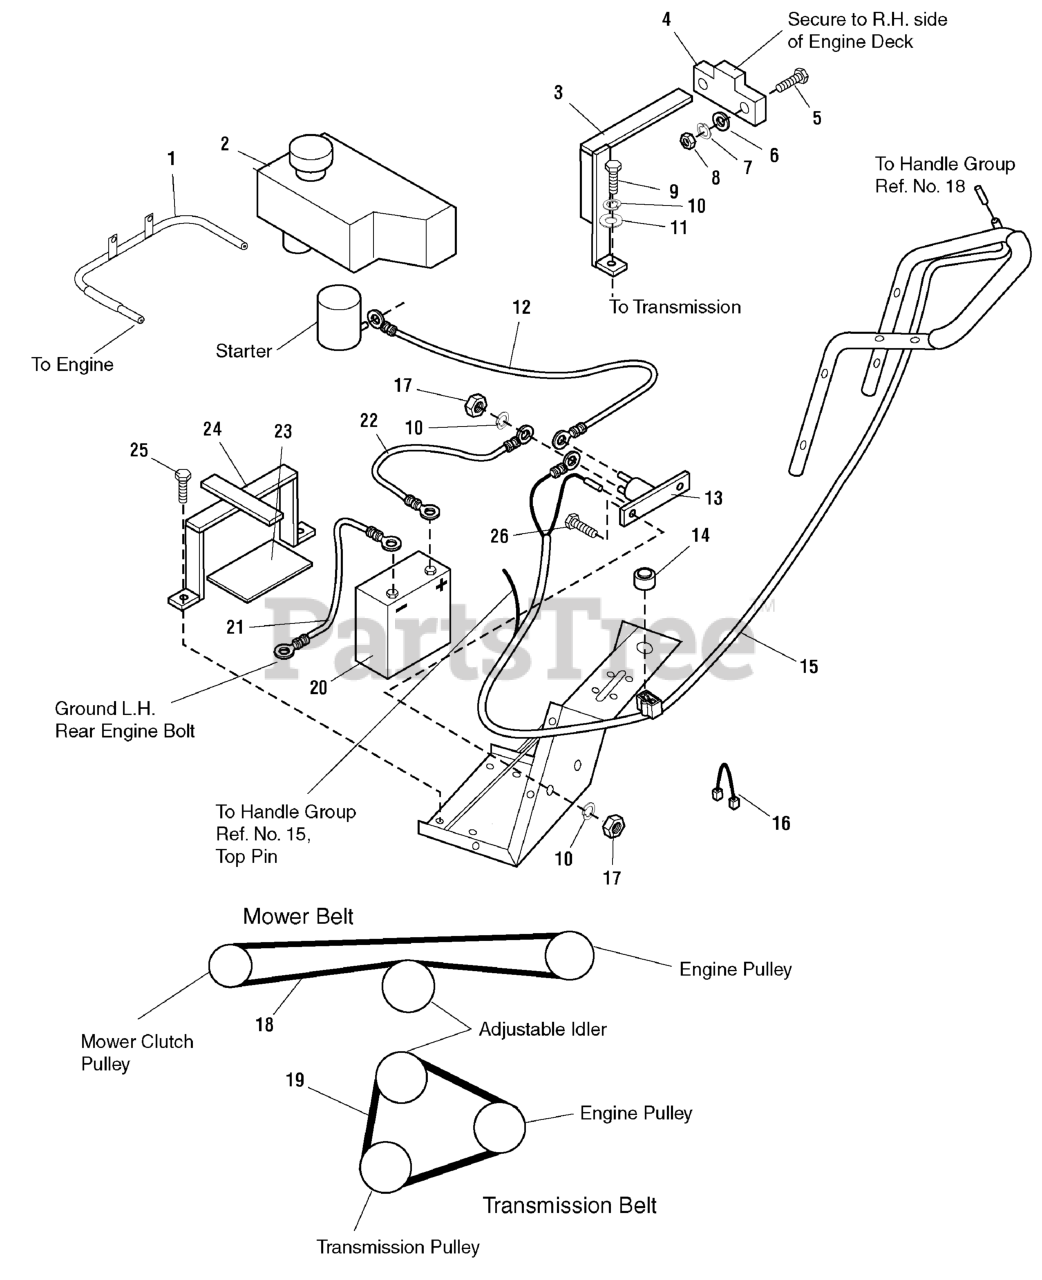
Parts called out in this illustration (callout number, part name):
1	Auxiliary Fuel Line w/Clamps - 9"
1	Auxiliary Fuel Line w/Clamps - 18"
2	TANK-FUEL
3	Bracket
4	Plate, Lock Engage / Disengage
5	BOLT, 5/16-18 x 3/4
6	Flatwasher, 5/16
7	Lockwasher, 5/16
8	NUT, Hex, 5/16-18
9	BOLT, 1/4-28 x 5/8
10	Lockwasher, 1/4
11	Flatwasher, 1/4
12	Cable - Solenoid to Starter Coil
13	Solenoid
14	Keyed start switch
14	Keyed off switch
14	Keyed off switch, Honda Models
15	Wire Harness, Honda
15	Wire Harness, Briggs & Stratton
15	Wire Harness, Kawasaki
16	Wire, Jumper, Honda Models
17	NUT, Hex, 1/4-20
18	Belt, Blade Clutch Drive
19	Belt, Transmission Drive
20	Battery
21	Cable, Battery Negative to Ground
22	Cable, Battery Positive to Solenoid
23	Battery Rubber
24	Battery Hold-Down
25	CAPSCREW, TEK, #12 x 3/4
26	BOLT, 1/4-20 x 3/4
